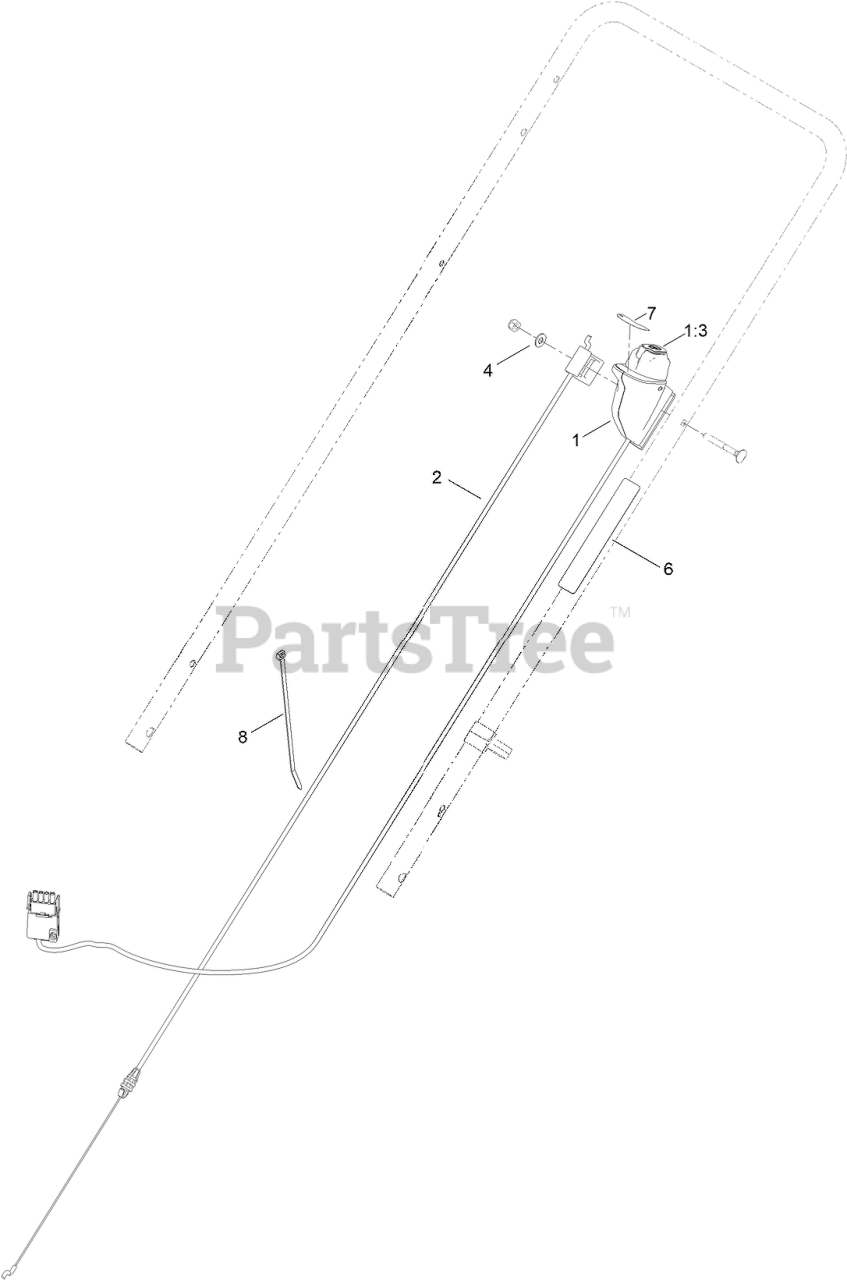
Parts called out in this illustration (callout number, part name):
1	SWITCH STARTER ASM
1:3	STARTER BUTTON, 2-SP
2	CABLE - BRAKE
4	WASHER-FLAT
6	DECAL-CONTROLS (60V START)
7	DECAL CONTROL SPEED
8	TIE-CABLE
